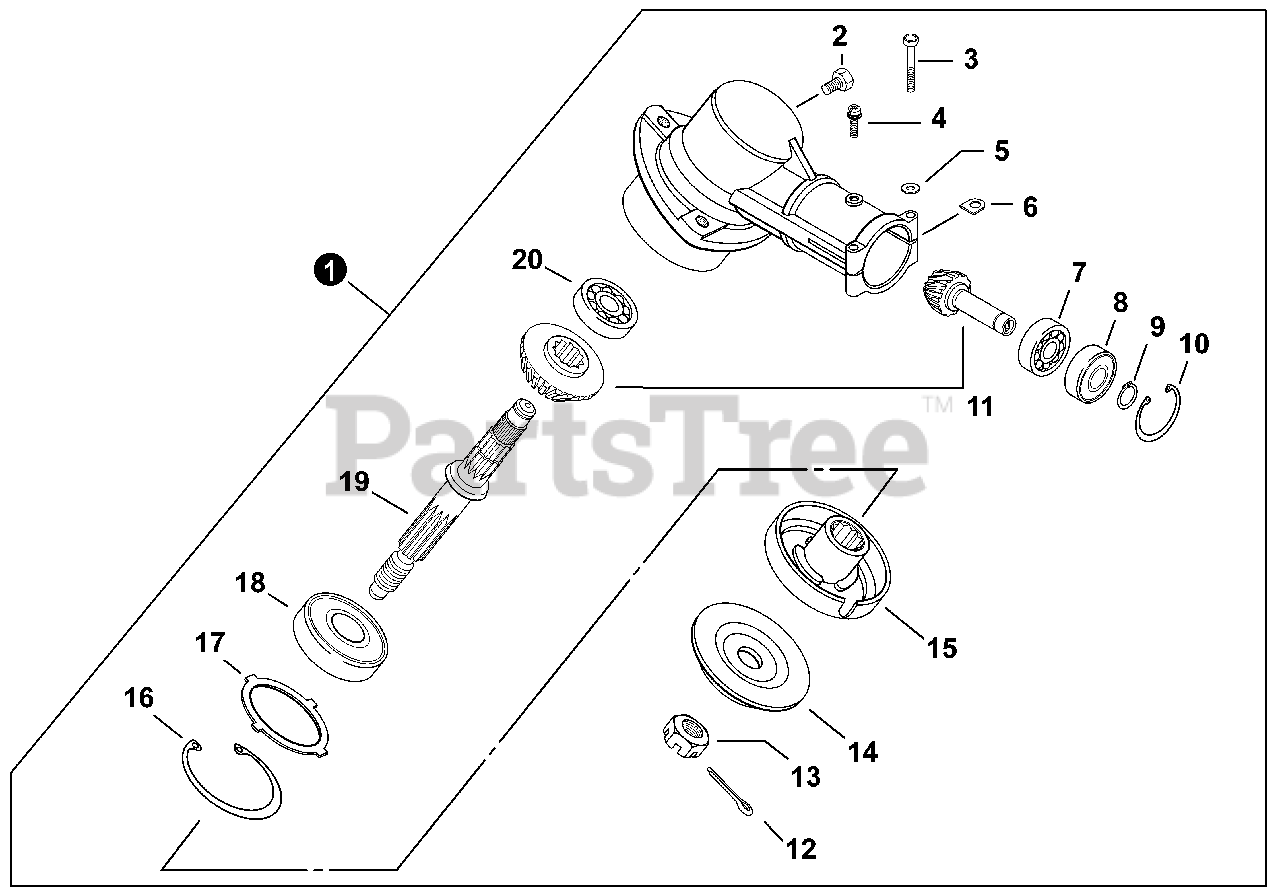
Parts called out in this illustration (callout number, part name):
1	GEAR CASE ASSY
2	BOLT M8×8
3	BOLT 5×35 SP
4	SCREW 5×10
5	WASHER, FLAT 5.5×10×0.8
6	D-WASHER
7	BEARING, BALL 6900
8	BEARING, BALL 6900Z
9	RING, SNAP Ø10
10	RING, SNAP Ø22
11	GEAR SET
12	PIN, COTTER 2×22
14	PLATE, ADAPTOR - LOWER
15	PLATE, ADAPTOR - UPPER
16	RING, SNAP Ø32
18	BEARING, BALL 6201
19	SHAFT, GEAR
20	BEARING, BALL 609
